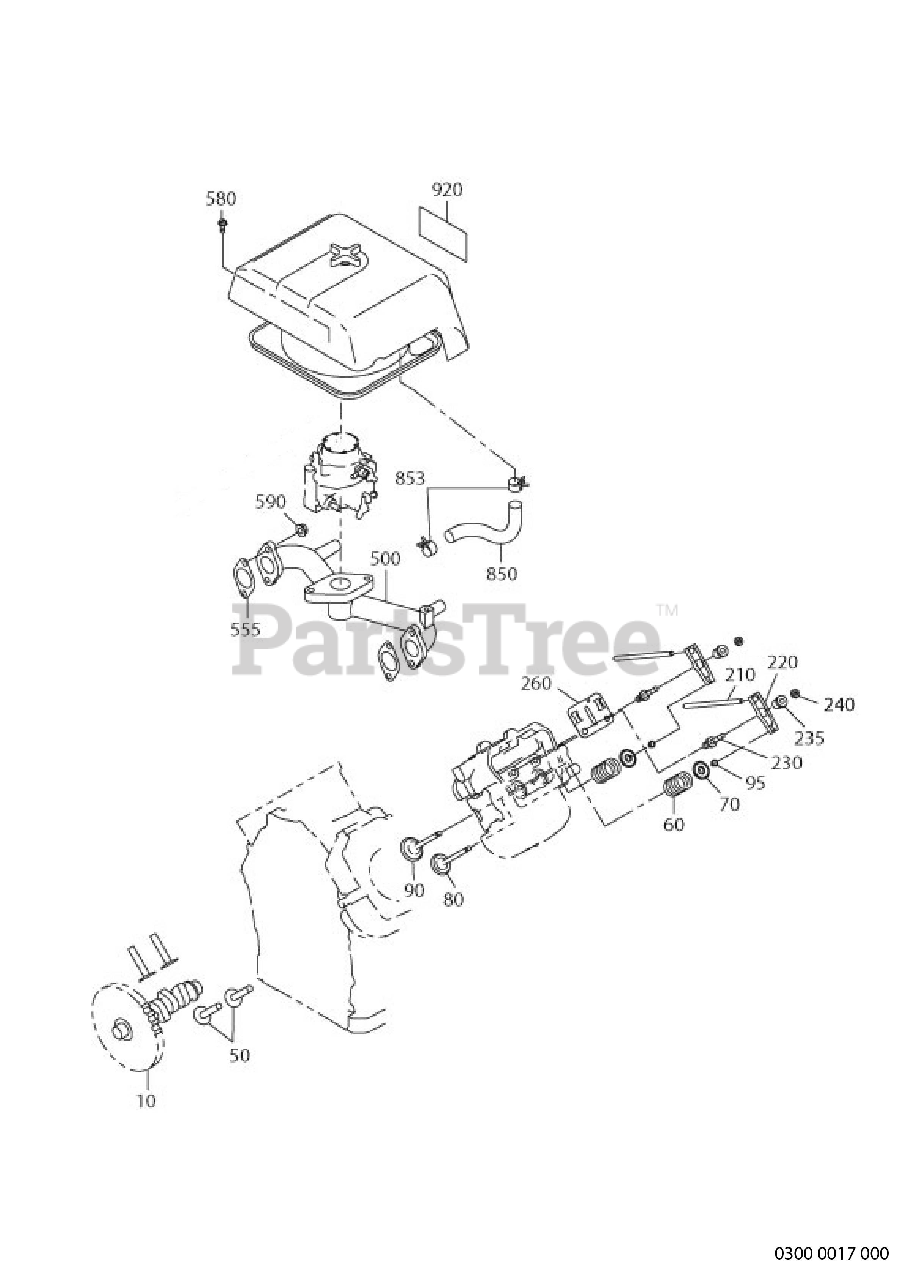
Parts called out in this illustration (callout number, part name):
70	SPRING RETAINER
500	INTAKE MANIFOLD
555	GASKET(IN MANIFOLD)
920	LABEL(TRADE MARK)
